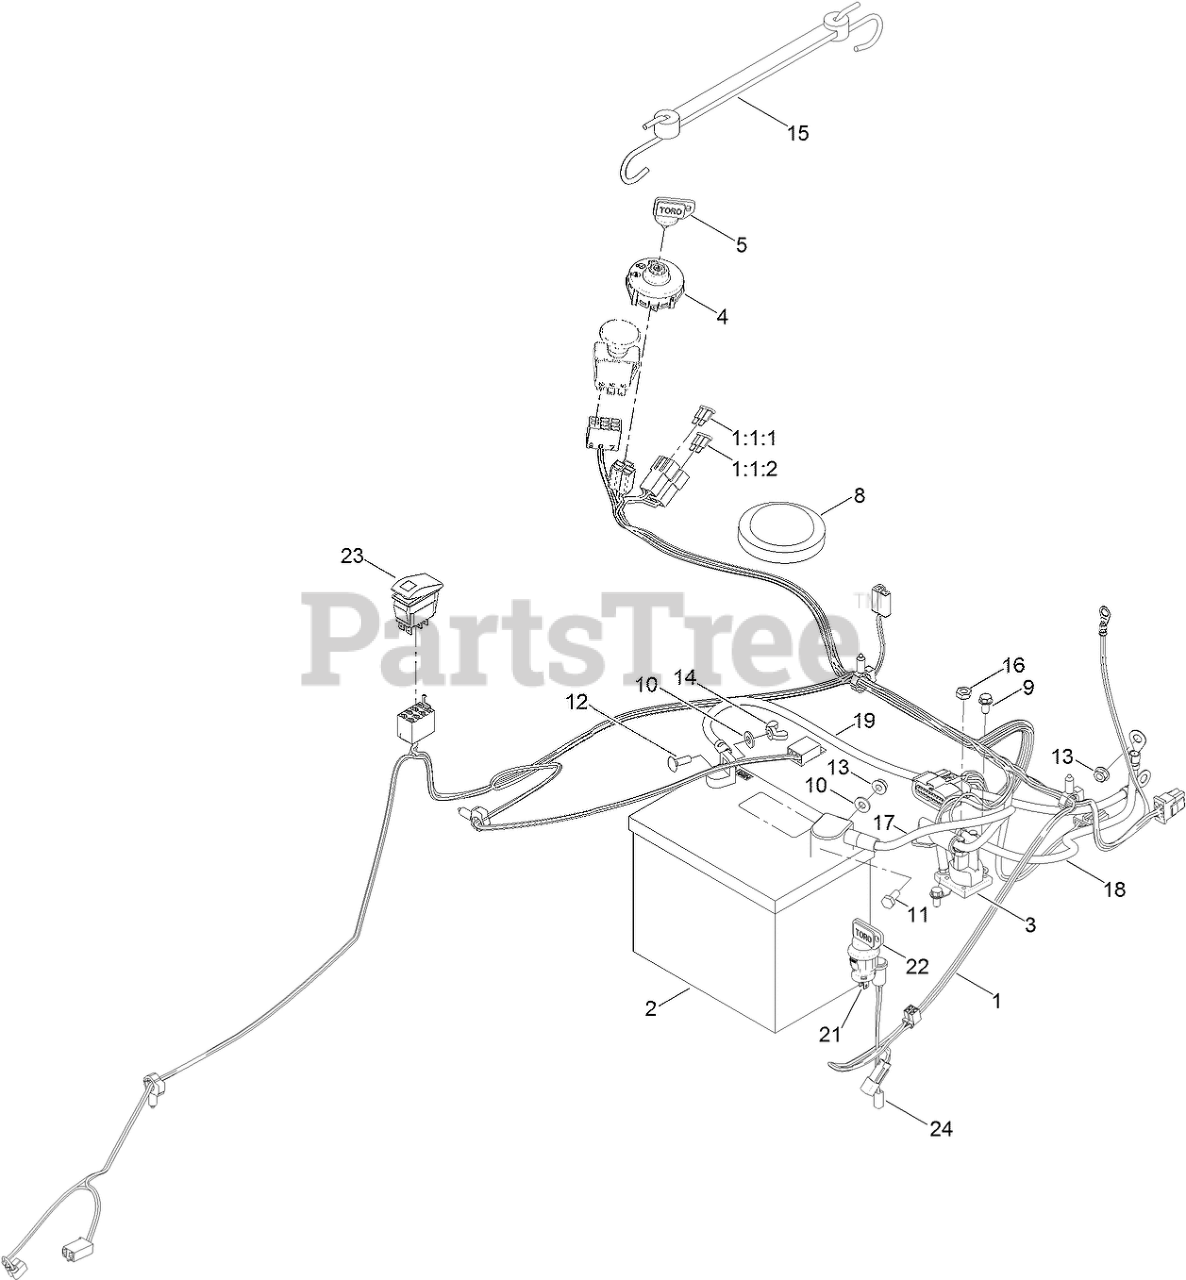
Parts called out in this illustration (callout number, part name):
1	HARNESS-WIRE
1:1	HARNESS-WIRE
1:1:1	FUSE-BLADE, 30 AMP
1:1:2	FUSE-BLADE, 25 AMP
2	BATTERY
3	SOLENOID
4	SWITCH-IGNITION
5	KEY-IGNITION
8	SWITCH-SEAT
9	SCREW-HWH
10	WASHER-FLAT
11	SCREW-HH
12	BOLT-CARR
13	NUT-HF
14	NUT-WING
15	HOLDDOWN-BATTERY
16	NUT-JAM
17	CABLE-BATTERY, RED
18	CABLE-BATTERY, POSITIVE
19	CABLE-BATTERY, BLACK
21	SWITCH-MOMENTARY, N.O.
22	KEY-TORO
23	Switch-Rocker, (ON)-Off-(ON)
24	LIGHT-INDICATOR
